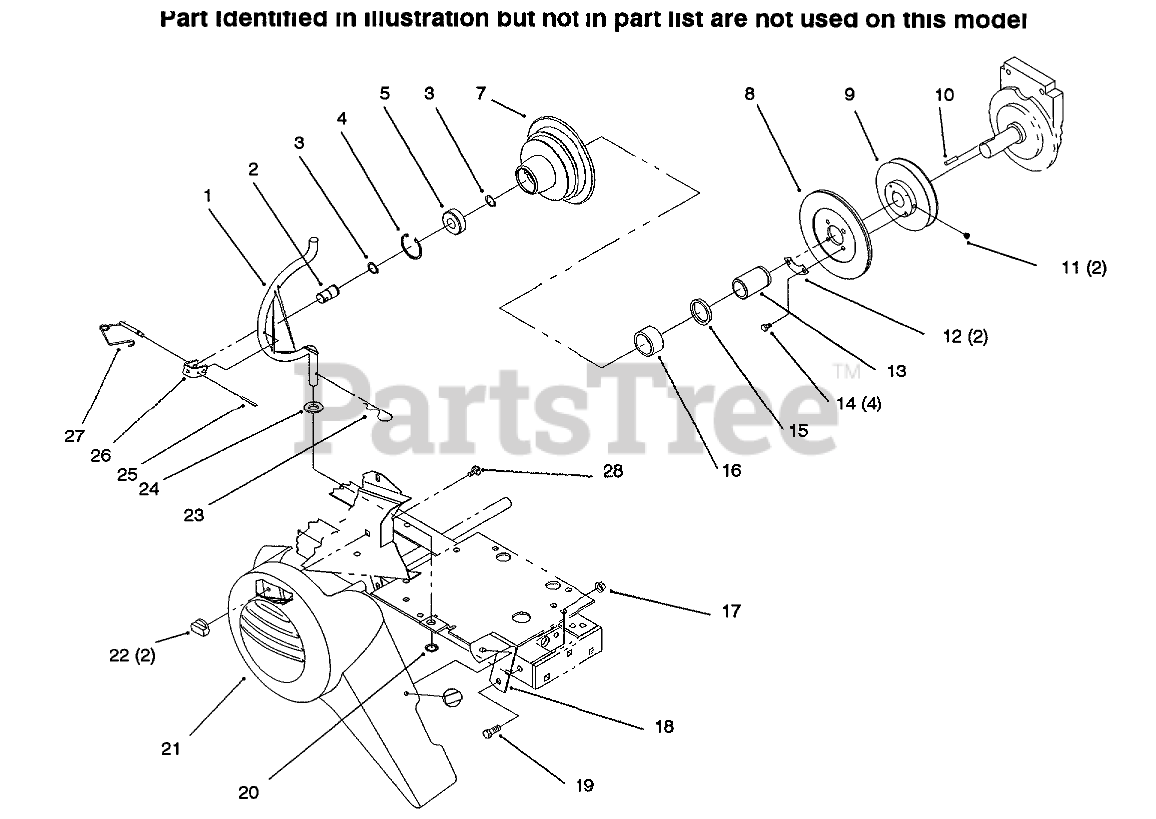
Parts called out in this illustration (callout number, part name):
1	ROD-HOUSING
2	SHAFT-PTO
3	Ring-Snap
4	RING-RETAINING
5	BEARING-BALL
7	Housing-Clutch
8	Facing-Clutch
8	ASS'Y-CLUTCH PLATE
9	PULLEY
11	SCREW-SET, HSH
12	RETAINER
13	RACE-BEARING
14	SCREW-HEX HD CAP
15	SEAL-OIL
16	Seal
17	NUT-FLANGE
18	Bracket
19	SCREW-HH
20	RING-REINFORCED CIRC
21	GUARD - BELT
22	NUT - WING
23	PIN-COTTER, HAIR
24	WASHER-FLAT
26	CLEVIS
27	LOCKING PIN ASM
28	Retainer-Bolt
